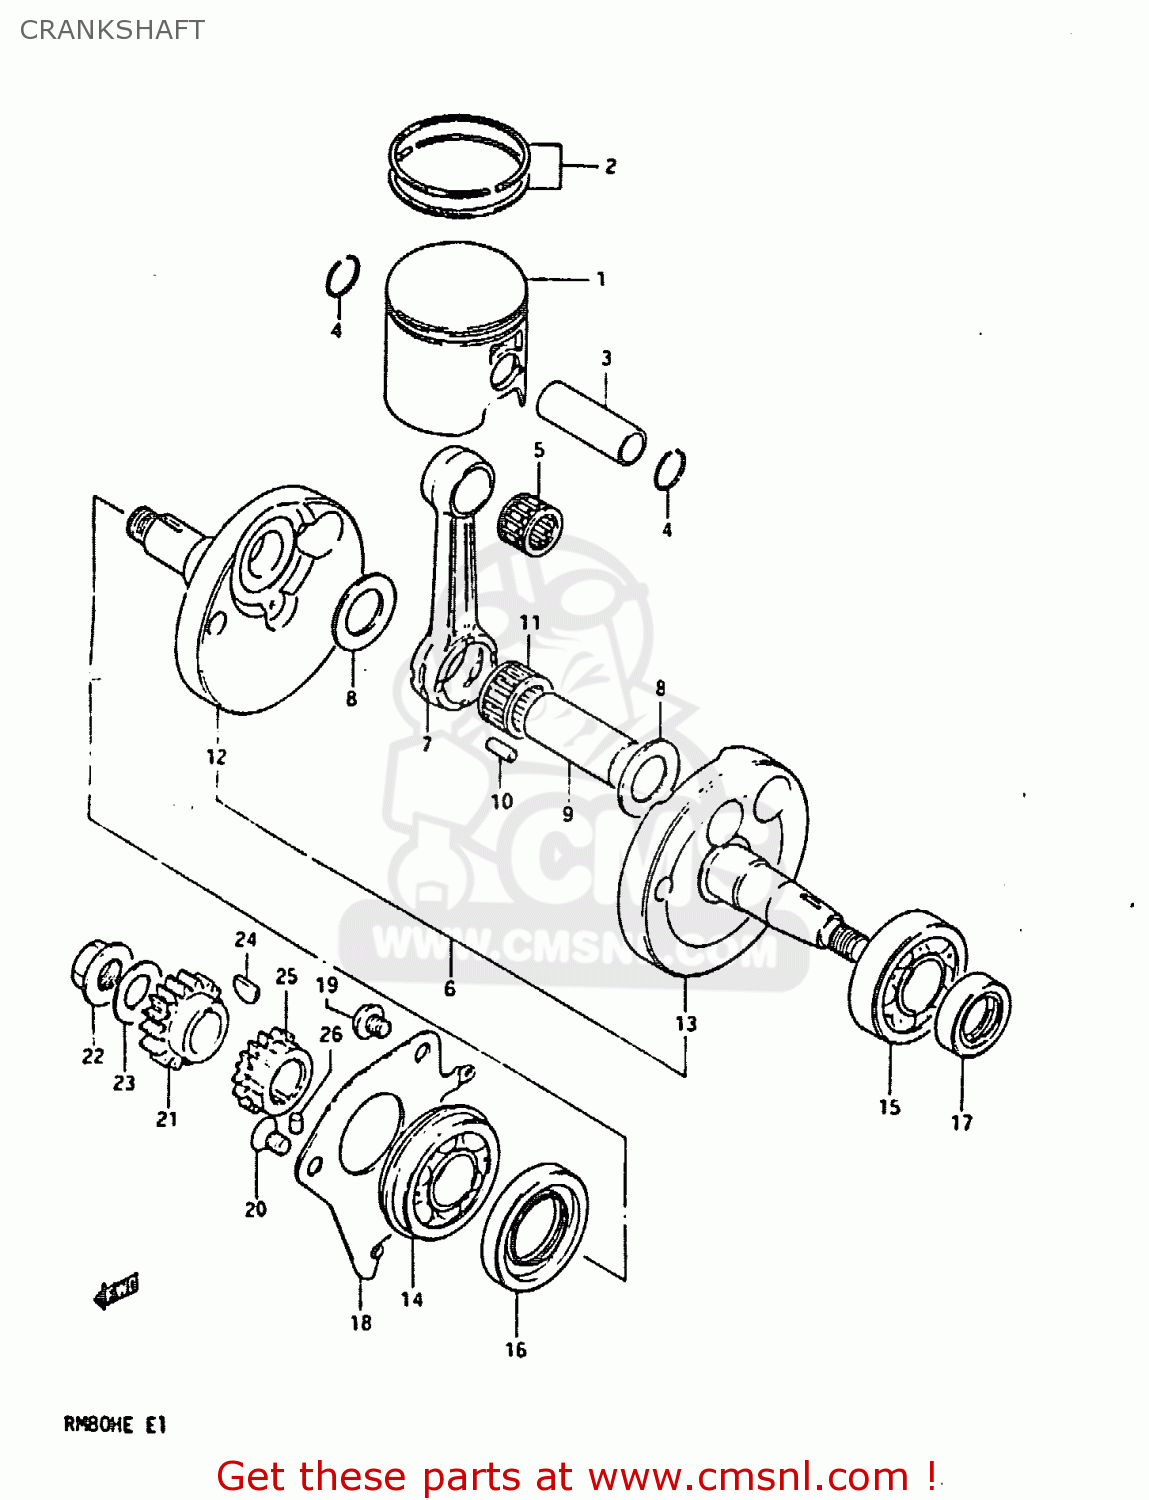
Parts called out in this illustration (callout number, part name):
1	PISTON
2	RING SET,PISTON
3	PIN,PISTON
4	RING,SNAP 14MM
5	BEARING(14X18X16)
6	CRANKSHAFT ASSEMBLY
7	CONNECTING ROD
8	WASHER
9	PIN,CRANK
10	ROLLER(3X11)
11	CAGE
12	CRANKSHAFT
13	CRANKSHAFT,LEFT
14	BEARING(20X47X14)
15	BEARING
16	SEAL,OIL(26X47X7.3)
17	SEAL,OIL(18X30X8)
18	PLATE,CRANKSHAFT BEARING
19	SCREW 6X12
20	SCREW
21	GEAR,PRIMARY DRIVE
22	NUT
23	WASHER
24	KEY
25	GEAR,WATER PUMP DRIVE
26	PIN 3X5
